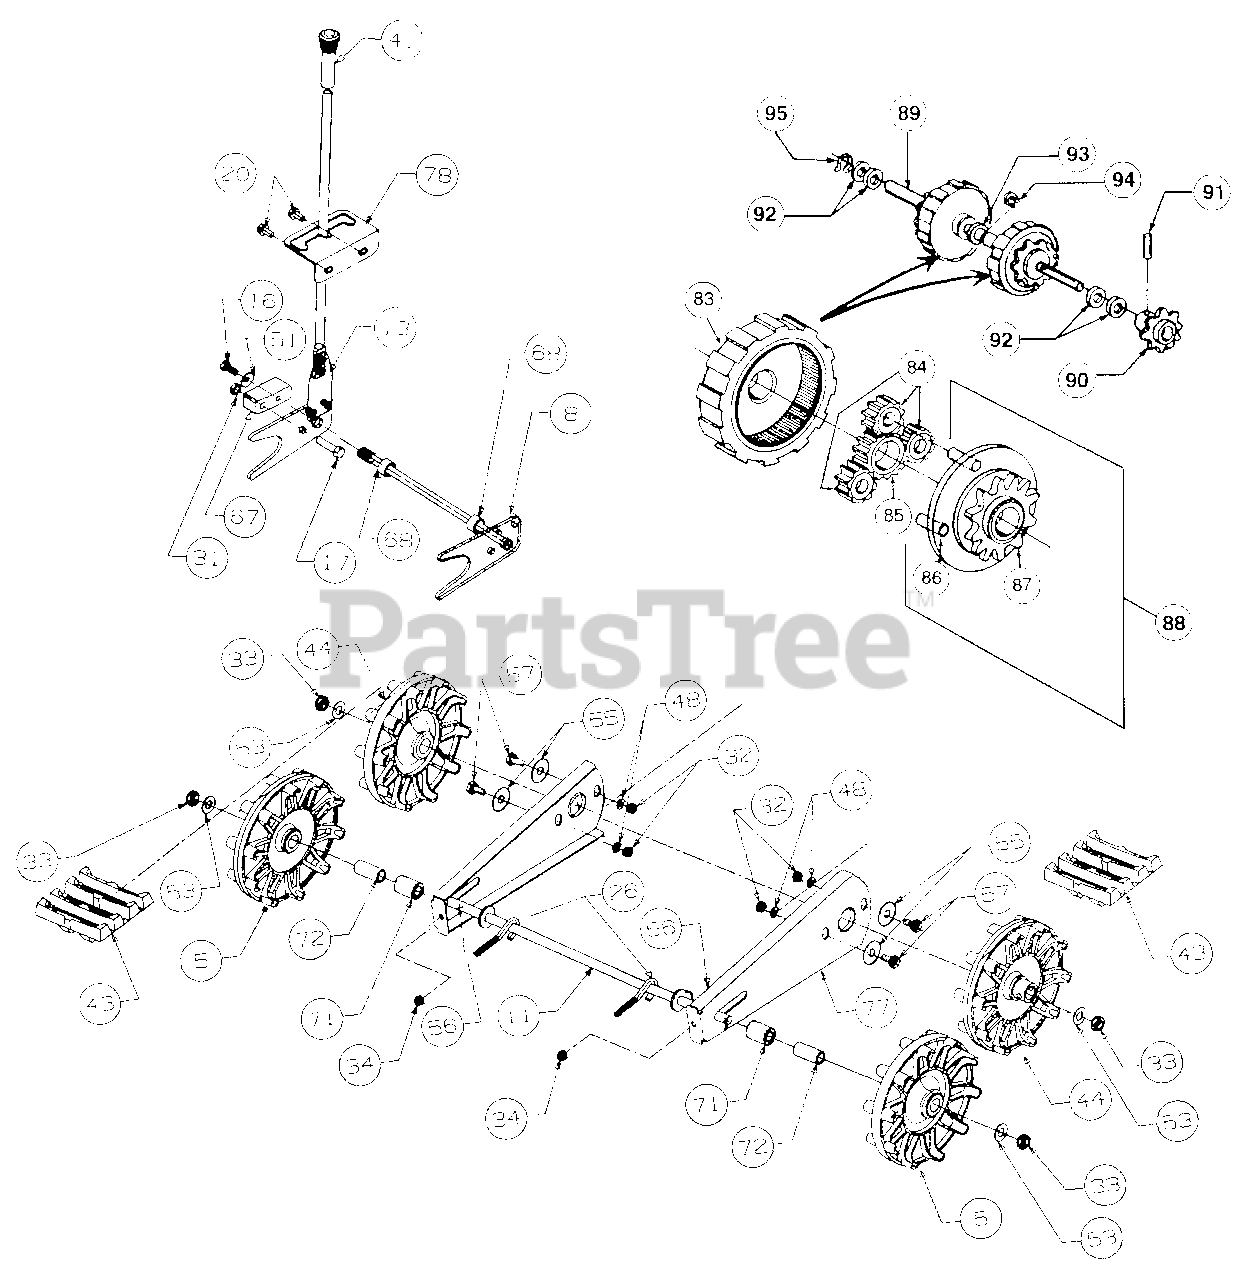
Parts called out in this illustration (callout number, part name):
5	Wheel Ass'y, Idler Track
16	Screw, Hex Cap 5/16-24 x .75 GR5
17	Screw, Hex Cap 3/8-24 x 1.5 GR5
20	Screw, Hex Wash Hd Tapp 5/16-16 x .62
26	Eye Bolt, 5/16-18 x 3.0
31	Nut, Hex Lock, 3/8-24
32	Nut, Hex, 5/16-18
33	Nut, Hex Insert Lock 1/2-20
34	Nut, Hex Insert Lock 5/16-18
43	Snow Track
44	Wheel, Track Drive
48	Washer, Lock, 5/16
51	Washer, Bell, .345 x .88 x .06
53	Washer, Flat, .51 x 1.0 x .06
55	Washer, Flat, .442 x 1.38 x .06
56	Lubricant
57	Shoulder Screw
67	Lift, Drive Shaft
68	Spacer, .632 x .875 x .5
71	Spacer, .510 x 1.0 x 1.34
72	Spacer, .51 x .75 x 1.67
83	Ring Gear
84	Gear, 12T
85	Gear, 18T
86	Dowel Pin
87	Carrier
88	Carrier Assembly
89	Drive Shaft
90	Sprocket, 13T
91	Pin, Spiral, 3/16 x 1.0
92	Washer, Flat, .58 x 1.12 x .02 Hdn
93	Washer, Flat, 5/8 x 1.0
94	Snap Ring, .625 Shaft
95	Snap Ring, .56 Dia. Shaft
